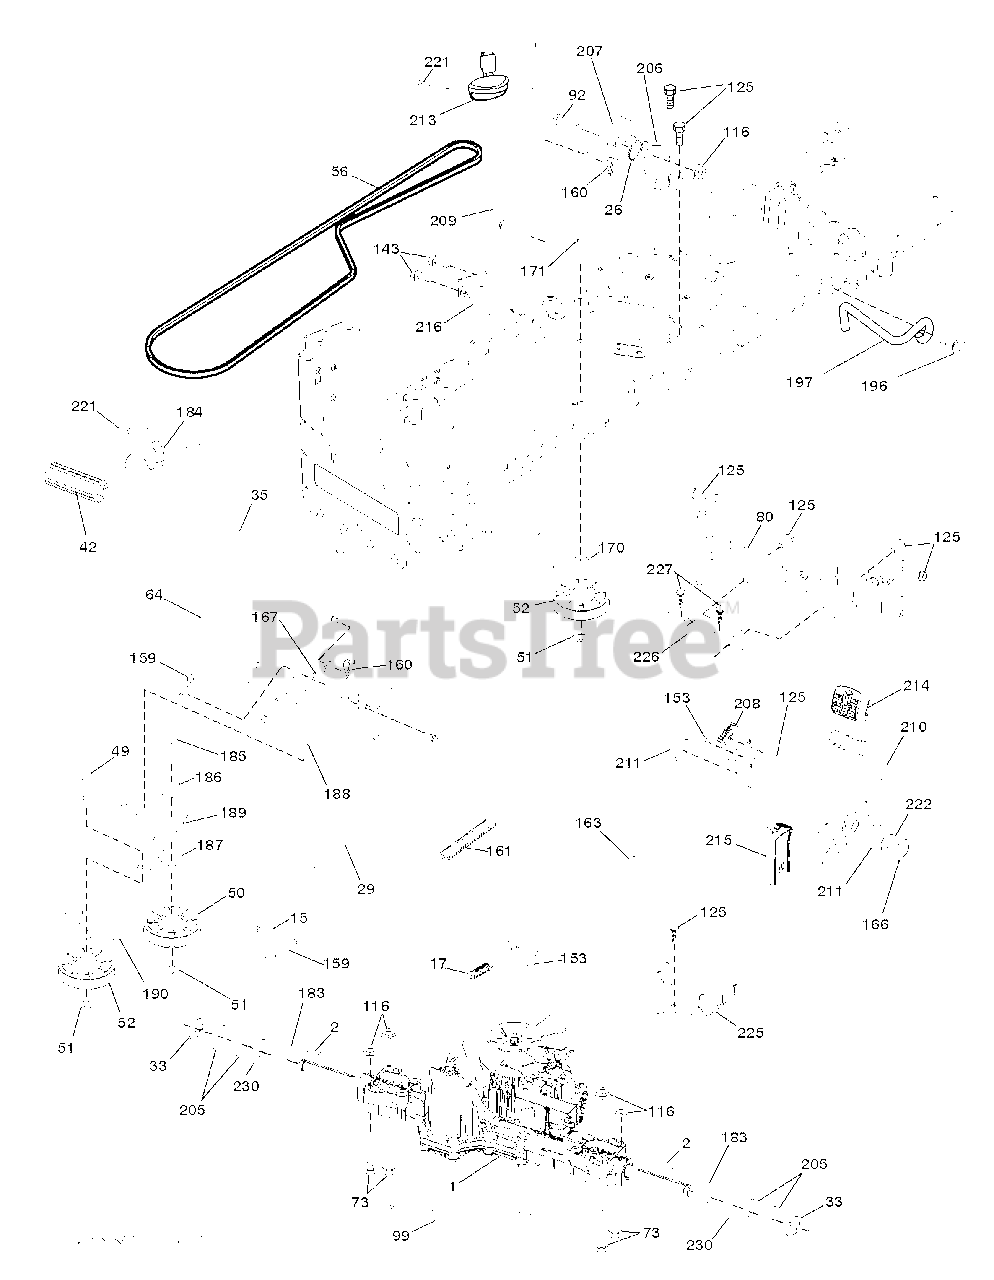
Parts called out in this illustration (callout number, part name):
2	SQUARE KEY
15	WASHER
17	SPRING.BRAKE.K46.GREEN
26	SPRING.RETURN.CRUISE
29	ROD.BRAKE.K46
35	ROD.BRAKE.PARTK.HUSQ.TEX
42	PEDAL COVER T
50	IDLER.FLAT.910.OFFSET
51	NUT LOCK FLG 3/8-16 UNC
52	IDLER.V-GROOVE.910.OFFSET
56	V-BELT.MOWER.92.40.42/K46
64	SHAFT.ASM.PEDAL.BRK.CNTR
80	STRAP TORQUE
92	BOLT
99	ROD.SPRING.BYPASS.K46.LT.Z
116	NUT LOCK HEX FLANGE 5/16-18
125	SCREW
143	SCREW LT
153	RETAINER M
159	COTTER PIN
160	RETAINER CLIP
161	SPRING, RETURN LT
163	ROD.CONTROL.PEDAL.K46
166	NUT.PUSH.625
167	LATCH.BRAKE.SPRING
170	KEEPER.V-IDLER.CENTER.
183	SPACER AXLE
184	RB HANDLE.PARKG.BRK.HUS/PRED
186	SPACER.RETAINER
187	WASHER 12/32X2X10GA
188	RP LINK.CLUTCH.GROUND.DRIVE
189	BELLCRANK.GROUND.DRIVE.TEX.
190	KEEPER.BELLCRANK.DRIVE
196	SCREW 3/8-16X1
197	LINK.CLUTCH.ANIT-ROTAT
206	BRKT.MOUNT.LATCH.CRUIS
207	LATCH.CONTROL.CRUISE
208	GEAR.SECTOR.CONTROL.CR
209	ROD.CONTROL.CRUISE.GT.
210	ROCKER.ASM.PEDAL.CONTR
211	BEARING.NYLON
213	KNOB.CONTROL.CRUSIE.HU
214	PEDAL.FORWARD.HUSQVARNA.DEALER
215	PEDAL.REVERSE.TEX.GT.4
216	BRACKET.PULLEY.IDLER.W/TEX
221	RETAINER.SPRING.CLIP.H
222	WASHER 21/32 X 1-1/4 X 10 GA.
225	KEEPER.BELT.TRANSAXLE.K46
226	BRACKET.MOUNT.TORQUE.K46.TLT
227	SCREW
230	WASHER.HARDENED
